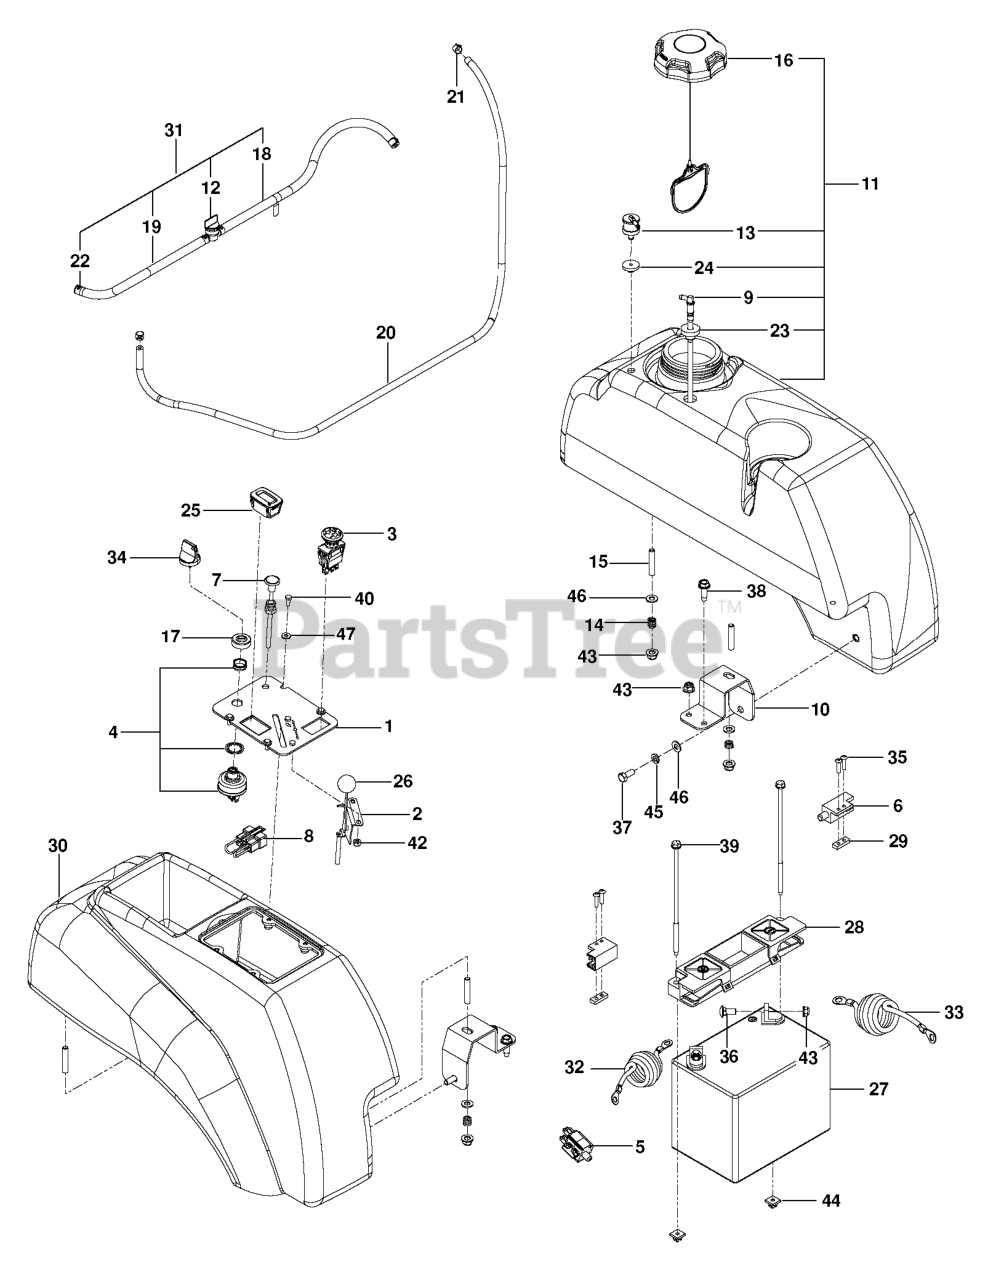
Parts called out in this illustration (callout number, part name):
2	THROTTLE CABLE
3	RP SWITCH.PTO.TERMINAL.STD.RED
4	SWITCH, IGNITION, INDAK
5	SWITCH, BRAKE 3P
6	SWITCH INTERLOCKT
7	CABLE, CHOKE, 38
8	PLUG, TIMER
9	FITTING, FUEL
10	SUPPORT, TANK, BLK
11	FUEL.TANK.ASSY.LH.MZ.GRY
12	FUEL VALVE
13	VALVE.FUEL.CHECK
15	STUD, 5/16C
16	CAP, FUEL
17	CAP IGNITION NUT
18	HOSE, FUEL .25 ID X 26"
19	GAS LINE 10"
20	HOSE.3/16"VAPOR.27"
21	CLAMP, HOSE
22	HOSE CLAMP
23	RUBBER GROMMET
24	GROMMET.CHECK.FUEL
25	GUAGE.SRVCMNDR.HRMTR.
26	KNOB.ROUND.BALL.BLACK
27	BATTERY, 12 V 330 AMP
28	BATTERY HOLD DOWN
29	TAPPED PLATE
30	FENDER CONSOLE
31	FUEL.HOSE.SHUT.OFF.ASM.10".26"
32	POST.CABLE LONG
33	NEG. CABLE, 28"
34	KEY, IGNITION
35	SCR #10-24 X .75 SKT HD BLK
36	BOLT 5/16C X 3/4" CARRIAGE
37	HCS 5/16C X 3/4
38	RP BLT 5/16-18 X 1 THRD FORM D
39	BOLT - 1/4-20 X 7.5
40	HCS #10-24 X 1/2
42	NUT 10-24 NYLOC
43	5/16-18 NYLOC FLANGE NUT
44	PUSH NUT-NYLON
45	WASHER.LOCK.HVY.HLCL.SPR.5/16
46	FLAT WASHER 5/16 SAE
47	WASHER #10
